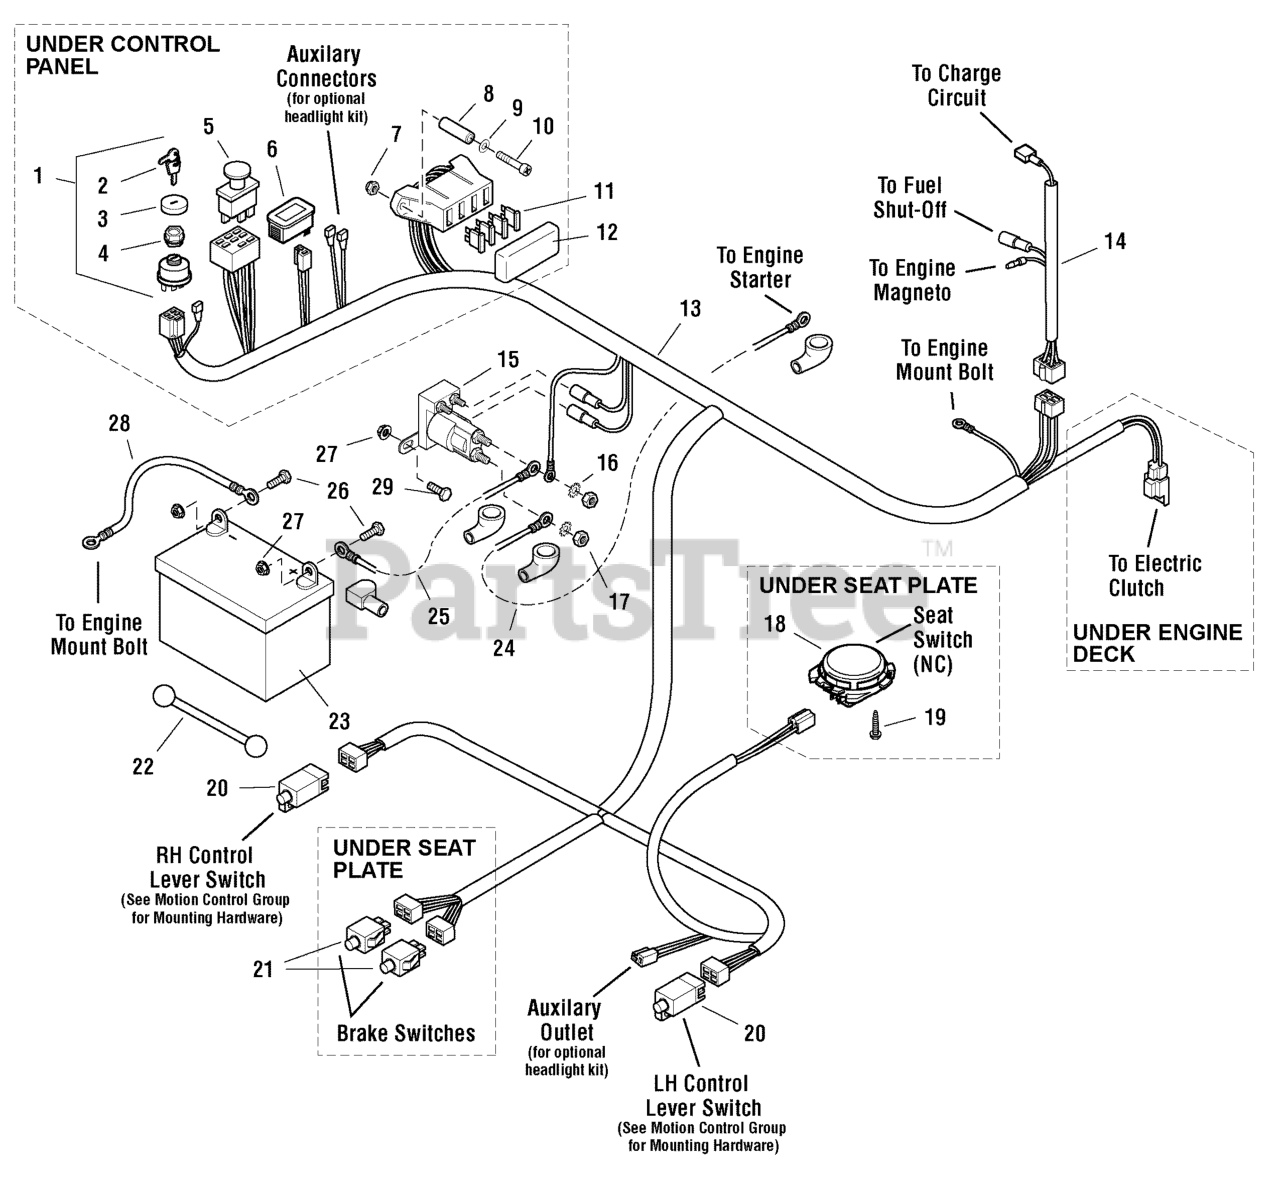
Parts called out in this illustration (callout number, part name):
1	SWITCH, IGNITION, 6 POST
2	KEY, IGNITION MOLDED SET
3	COVER, PLASTIC, SNAP ON
4	PLASTIC NUT
5	SWITCH, BLADE ENGAGEMENT
6	HOURMETER, Digital
7	NUT, #10-24 Hex Nylon Lock
8	SPACER, .20 X .38 X 1.25
9	WASHER, #10 SAE
10	SCREW, #10-24 x 2"
11	FUSE, 20A
12	FUSE BLOCK COVER
13	HARNESS ASSEMBLY, Main
14	ENGINE HARNESS
15	SOLENOID
16	WASHER, Light Lock, 5/16
17	NUT, Hex Jam, 5/16-24
18	SWITCH, NC, W/ BOLT-IN BASE
19	BOLT, Hex Washer Head PLASTITE, 1/4 X 1/2
20	SWITCH, PLUNGER, N.O./N.C.
21	SWITCH, DP NO/NC SNAP-IN
22	STRAP, BATTERY, 14 LONG, Rubber
23	BATTERY, Lawn & Garden, 12V (BCIU1, 340 CCA)
24	POSITIVE (+) BATTERY CABLE, 22"
25	POSITIVE (+) BATTERY CABLE, 22"
26	BOLT, 1/4-20 x 3/4
27	NUT, 1/4-20 HEX SERR. FLANGE
28	CABLE, Ground
29	HHCS, 1/4-20 X 0.625, GR5, ZINC/CLEAR
